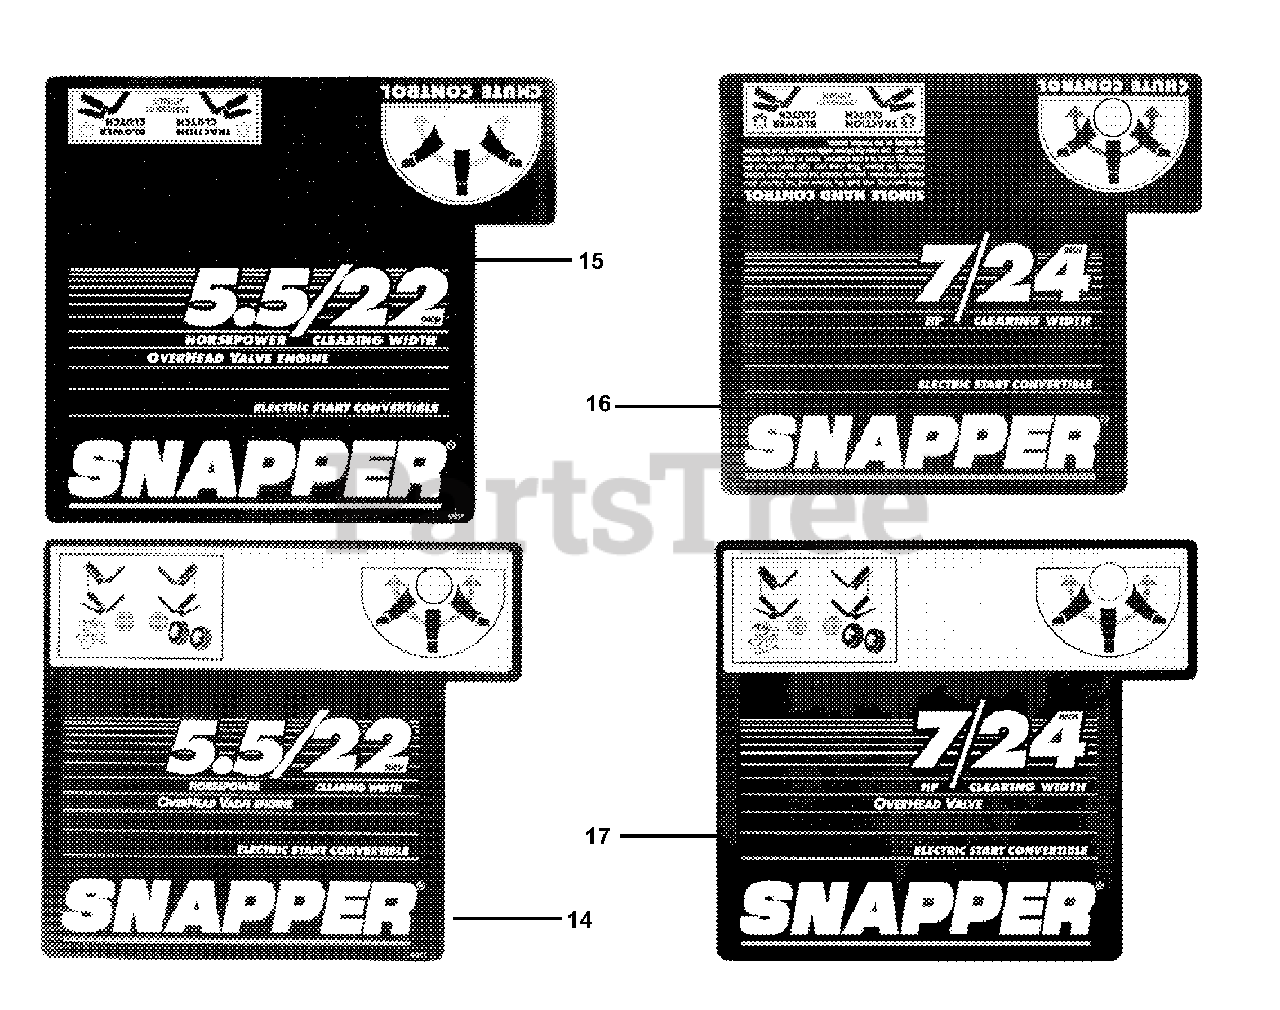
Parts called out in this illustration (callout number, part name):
14	DECAL, Control- E5.5/22
15	DECAL, Control- 5.5/22
16	DECAL, Control- 7/24
17	DECAL, Control- E7/24
